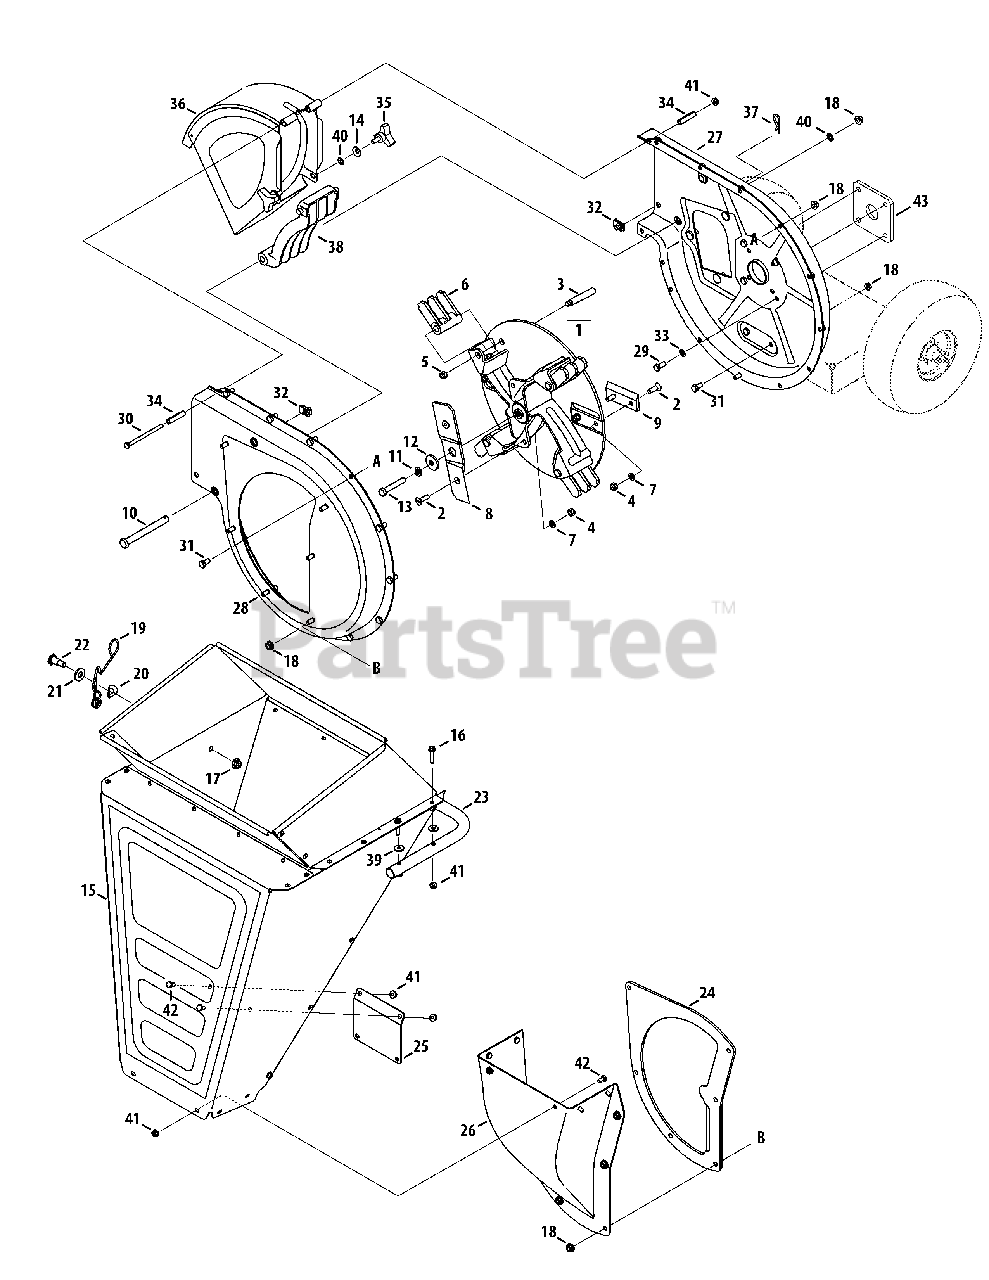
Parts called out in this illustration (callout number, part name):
1	Impeller Assembly Complete
2	Machine Screw, 5/16-24 x 1.0
3	Shoulder Pin, .5 x 2.625
4	Hex Lock Nut, 5/16-24
5	Nut, Jam Lock, 3/8-16
6	Flail Blade
7	Lock Washer, 5/16
8	Shredder Blade
9	Chipper Blade
10	Clevis Pin,.50 x 4.62
11	Lock Washer, 3/8
12	Flat Washer,.406 x 1.25
13	Hex Cap Screw, 3/8-24 x 2.2
14	Bell Washer.340 ID x.872 OD
15	Shredder Hopper Assembly
16	Hex Cap Screw, 1/4-20 x 1.250
17	Flange Lock Nut, 3/8-16
18	Flange Lock Nut, 5/16-18
19	Torsion Spring
20	Spring Washer,.50 x 1.0 x.022
21	Flat Washer,.50 x 1.0 x.0125
22	Shoulder Screw, 3/8-16,
23	Hopper Handle
24	Shredder Plate
25	Hopper Support Bracket
27	Inner Flail Housing Assembly
28	Outer Flail Housing Assembly
29	Hex Cap Screw, 5/16-24 x .75
29	Hex Cap Screw 5/16-24 x 1.00
30	Hex Cap Screw, 1/4-20 x 3.75
31	Hex Cap Screw, 5/16-18 x .625
32	U-Nut, 5/16-18
33	Lock Washer, 5/16
34	Hinge Spacer,.265 x.380 x 1.66
35	Knob, 5/16-18
36	Chute Deflector Assembly
37	Internal Cotter Pin
38	Shredder Screen
39	Flat Washer, .28 x .74 x .063
40	Speed Nut,.3125ID
41	Nut, Flange, Lock, 1/4-20
42	TT Screw, 1/4-20 x .5
43	Engine Plate
